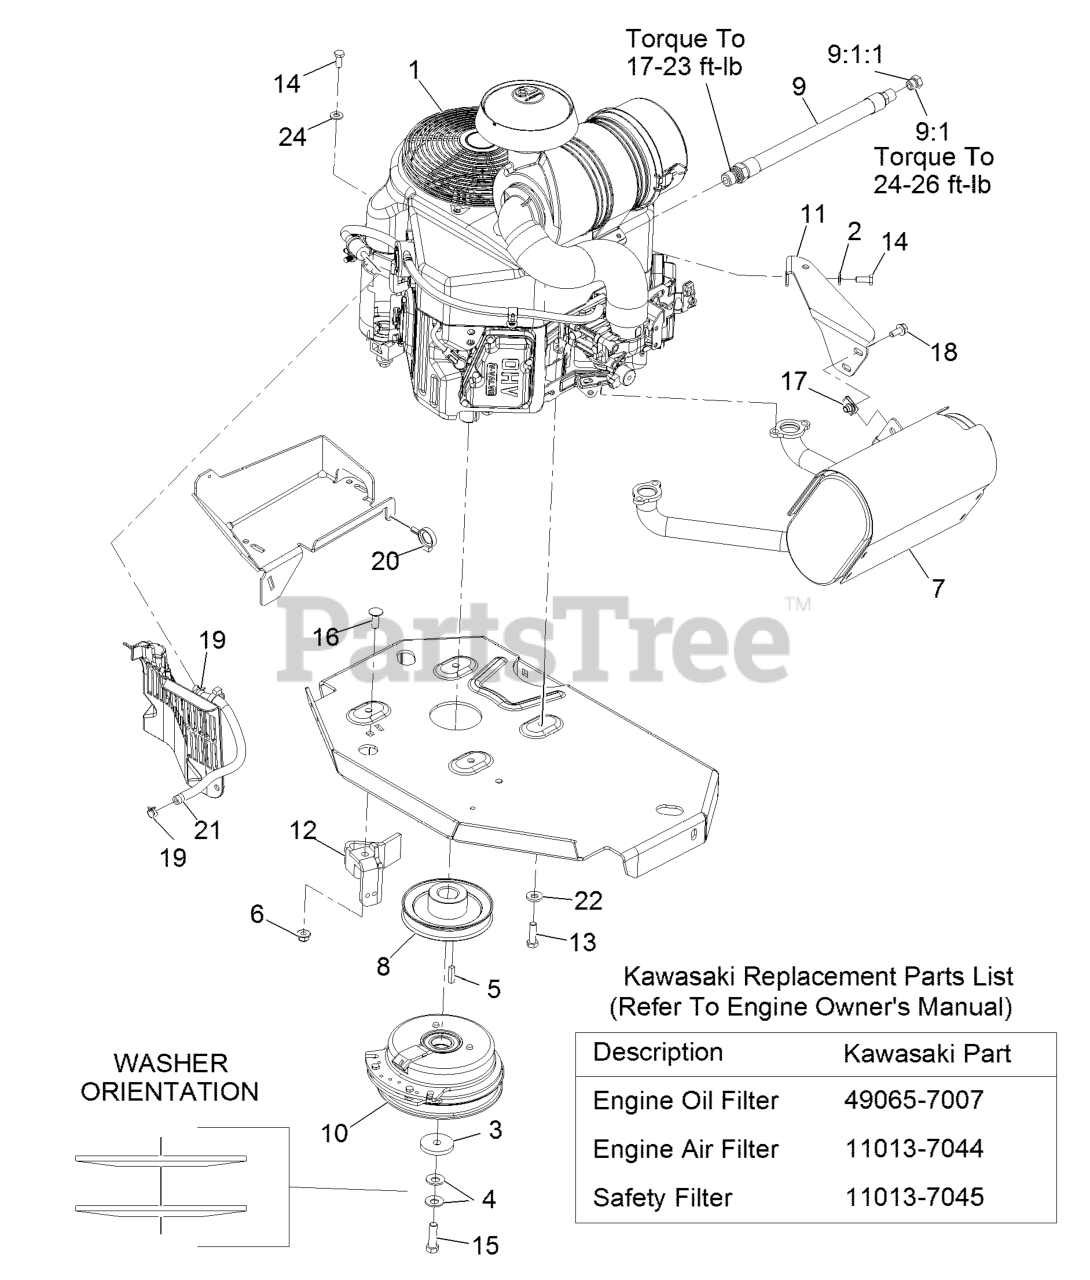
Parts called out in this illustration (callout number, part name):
2	WASHER-SPRING
3	WASHER-CLUTCH
4	WASHER-SPRING
6	NUT-HF, NI
7	MUFFLER
8	SHEAVE
9	ENGINE OIL DRAIN HOSE ASM
9:1	PLUG-HH
9:1:1	O-RING
10	CLUTCH KIT
11	BRACKET-MUFFLER
12	CLUTCH-ANCHOR
13	SCREW-HH
14	SCREW-HH
15	SCREW-HH 7/16-20 X 1 1/2 W/LOCTITE
16	SCREW-CARR
18	SCREW-HHF
19	CLAMP-HOSE
20	CLAMP-HOSE
21	HOSE-FUEL
22	WASHER-BELLEVILLE
24	WASHER-PLAIN
